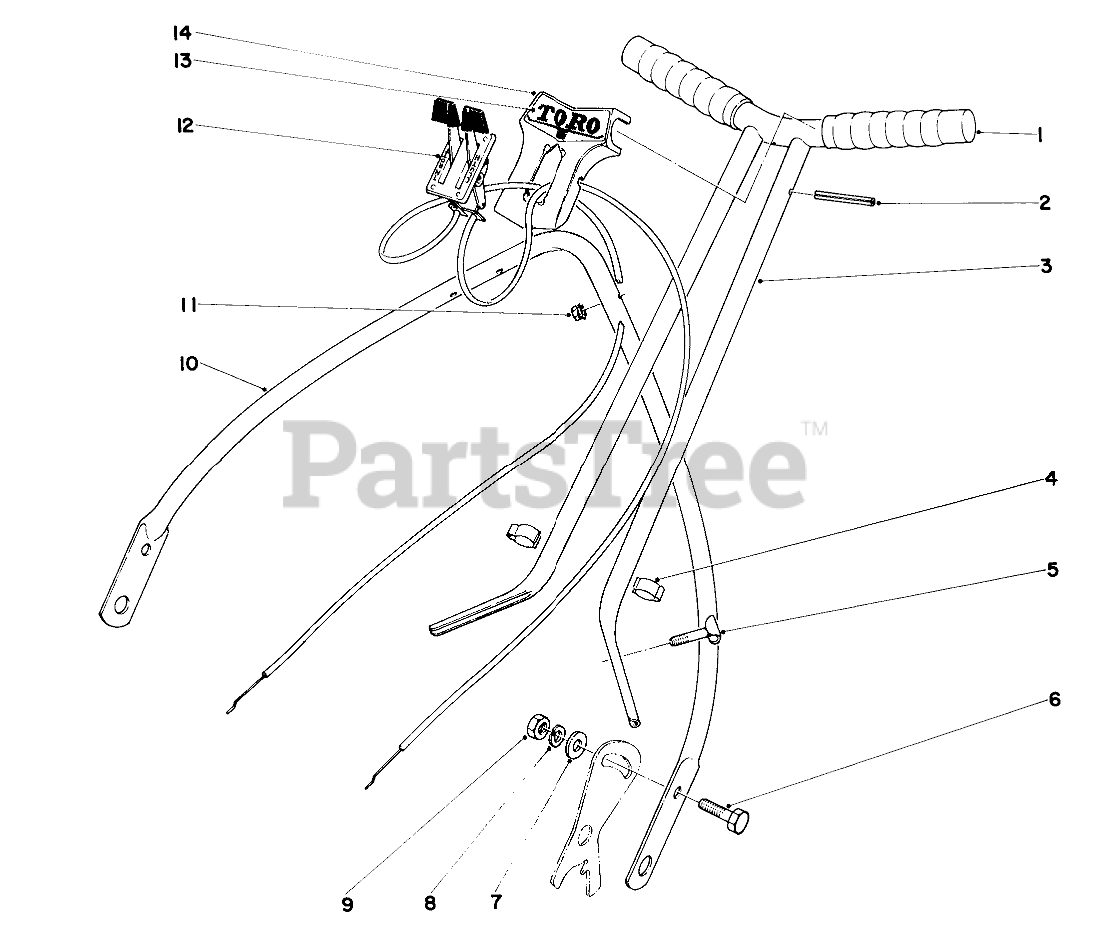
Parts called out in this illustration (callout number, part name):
1	Handle Clip
2	PIN-ROLL
3	Upper Handle
4	CONTROL WIRE CLIP
6	SCREW-HH
7	WASHER-PLAIN
8	WASHER-LOCK
9	NUT-HEX
10	Lower Handle
11	NUT-KEPS
12	Control Assembly
13	Decal
14	Cover Plate
